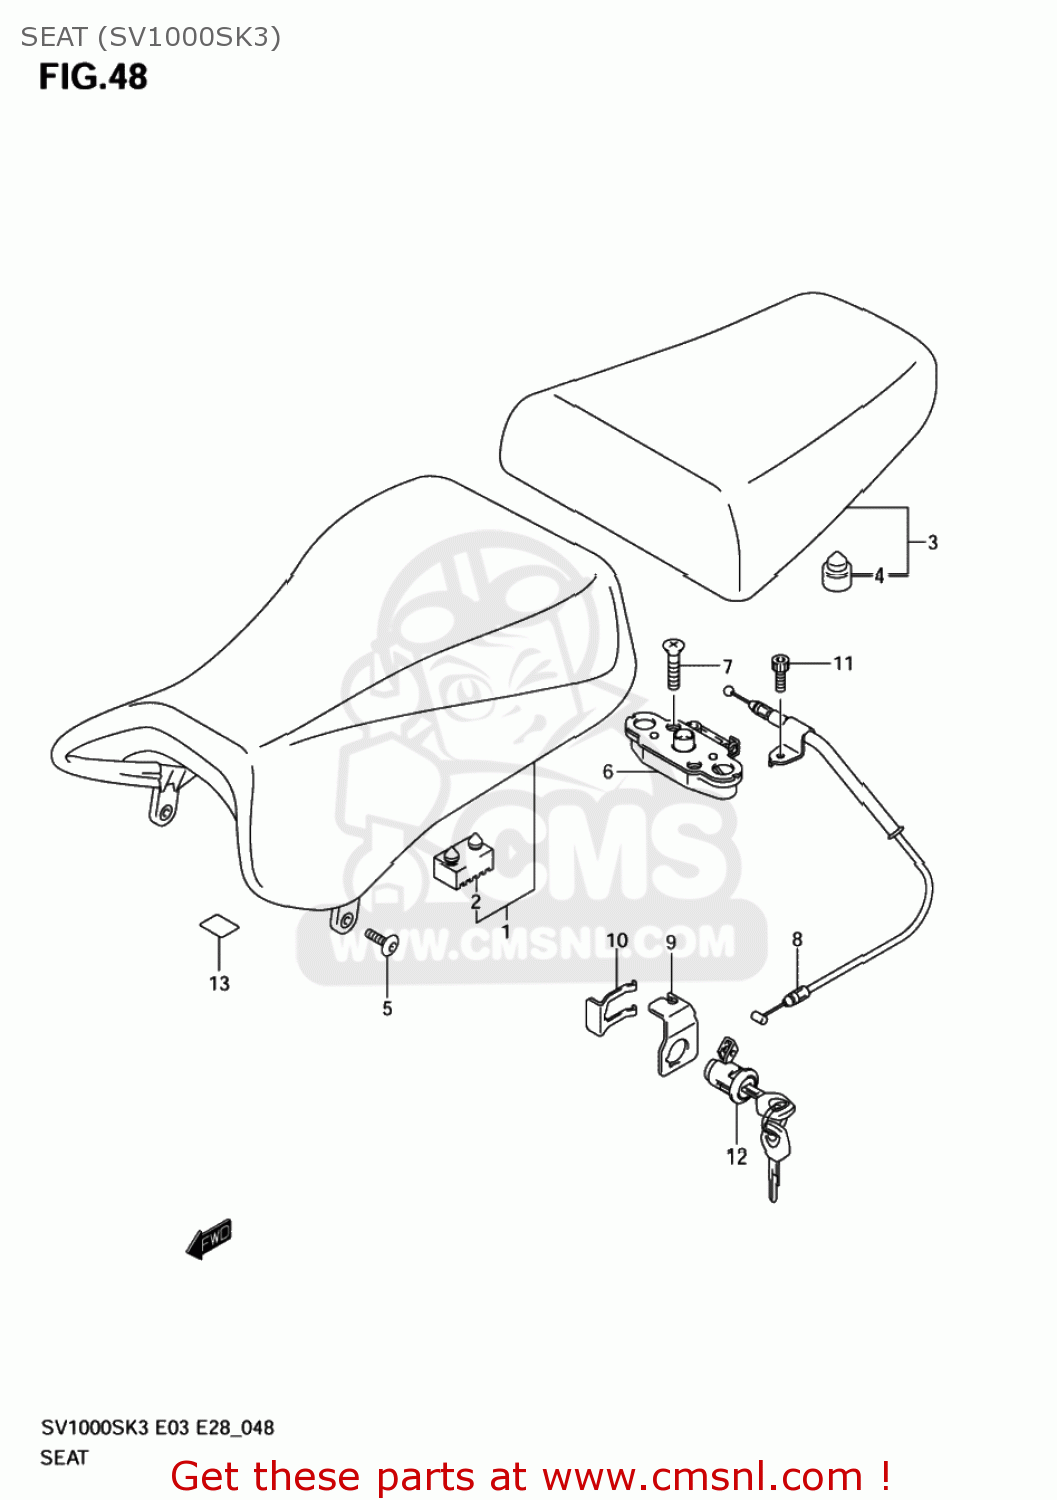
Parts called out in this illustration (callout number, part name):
1	SEAT ASSY(BLACK)
2	CUSHION
3	SEAT ASSY,PILLION
4	CUSHION
5	BOLT(6X18)
6	BRACKET,SEAT SUPPORT,RIGHT
7	SCREW
8	CABLE,SEAT LOCK
9	GUIDE,SEAT LOCK CABLE
10	PLATE,SEAT LOCK ASSY
11	BOLT,STRANGER
12	LOCK SET,SEAT
13	TAPE,FUEL TANK
